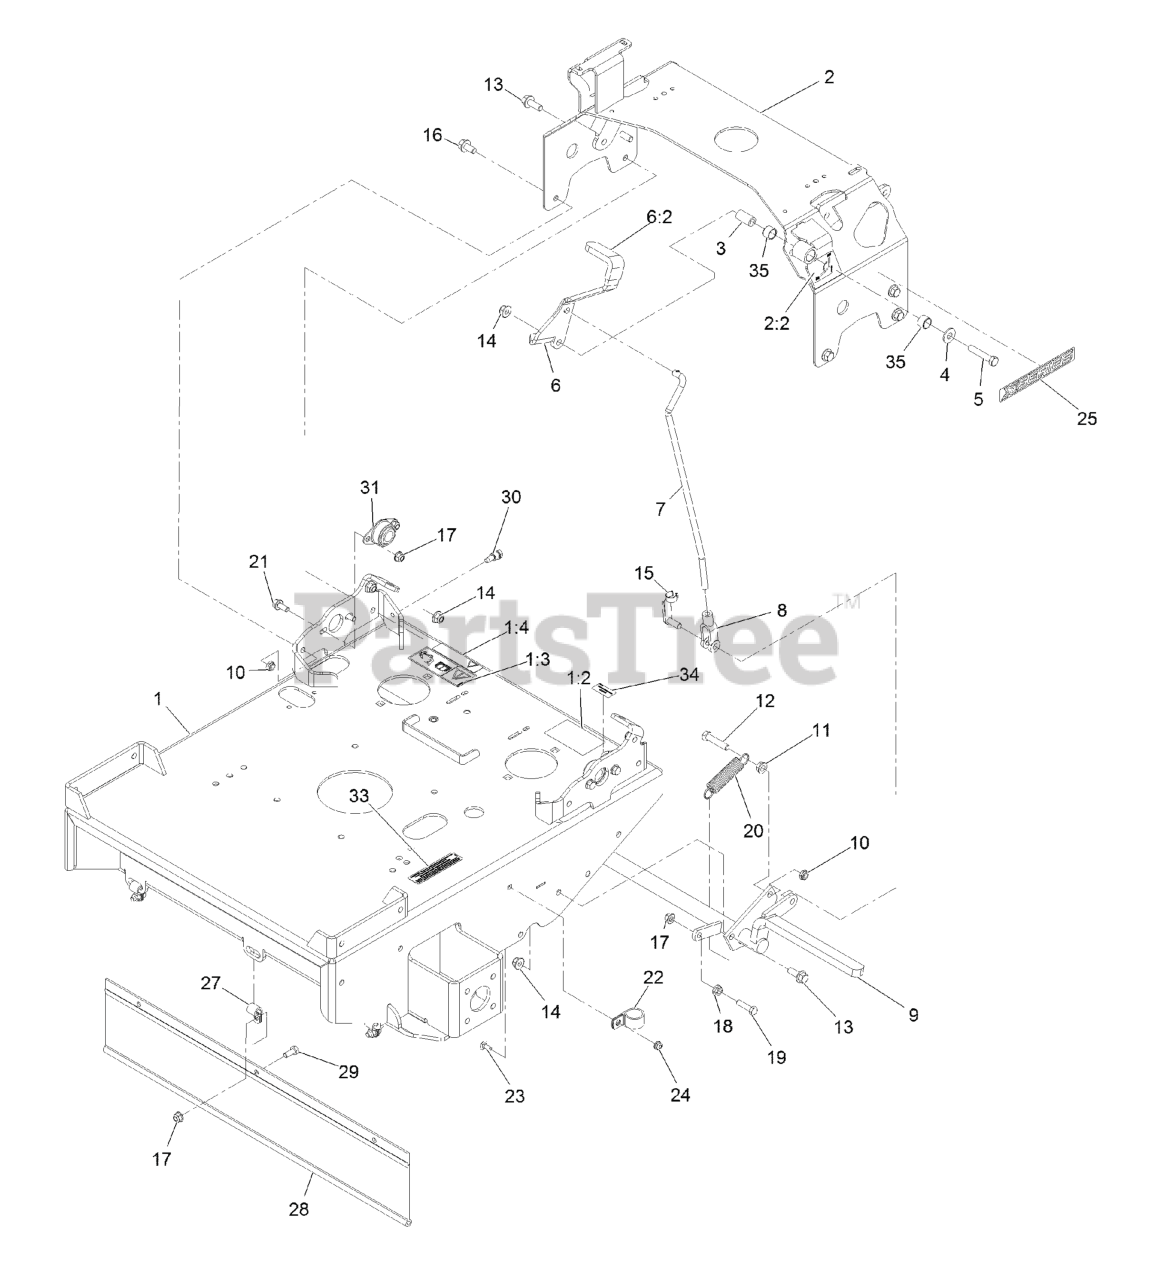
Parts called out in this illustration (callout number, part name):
1	ASM, ENGINE DECK W/ DECAL
1:2	DECAL-WARNING
1:3	DECAL-WARNING, SULKY
1:4	DECAL-DRIVE RELEASE
2	ASM, TANK SUPPORT W/ DECA
2:2	DECAL-PARK BRAKE, CE
3	BUSHING-PIVOT
4	WASHER-FLAT
5	SCREW-HH
6	ASM, BRAKE LEVER W/ GRIP
6:2	GRIP-LEVER
7	LINKAGE-BRAKE
8	YOKE-LINKAGE, BRAKE
9	WLD,BRAKE TTX
11	NUT-HHF, WHIZ
12	SCREW-HH
13	SCREW-HHF 3/8-16 X 1
14	NUT-HF, NI
15	PIN-SPRING, CLEVIS
16	SCREW-HHF
17	NUT-HF, NI
19	SCREW-HH
20	SPRING-IDLER
21	SCREW-HHF
22	CLIP-LOOM
23	SCREW-CARR
25	DECAL-X-SERIES
27	CLIP-LOOM
28	SHIELD,DRAG
29	SCREW-HH
30	BOLT-SHOULDER
31	BEARING-FLANGE, SIDE
33	DECAL-ARRESTOR, SPARK
34	Decal-Patent Ttco.Com
35	SLEEVE-BUSHING
